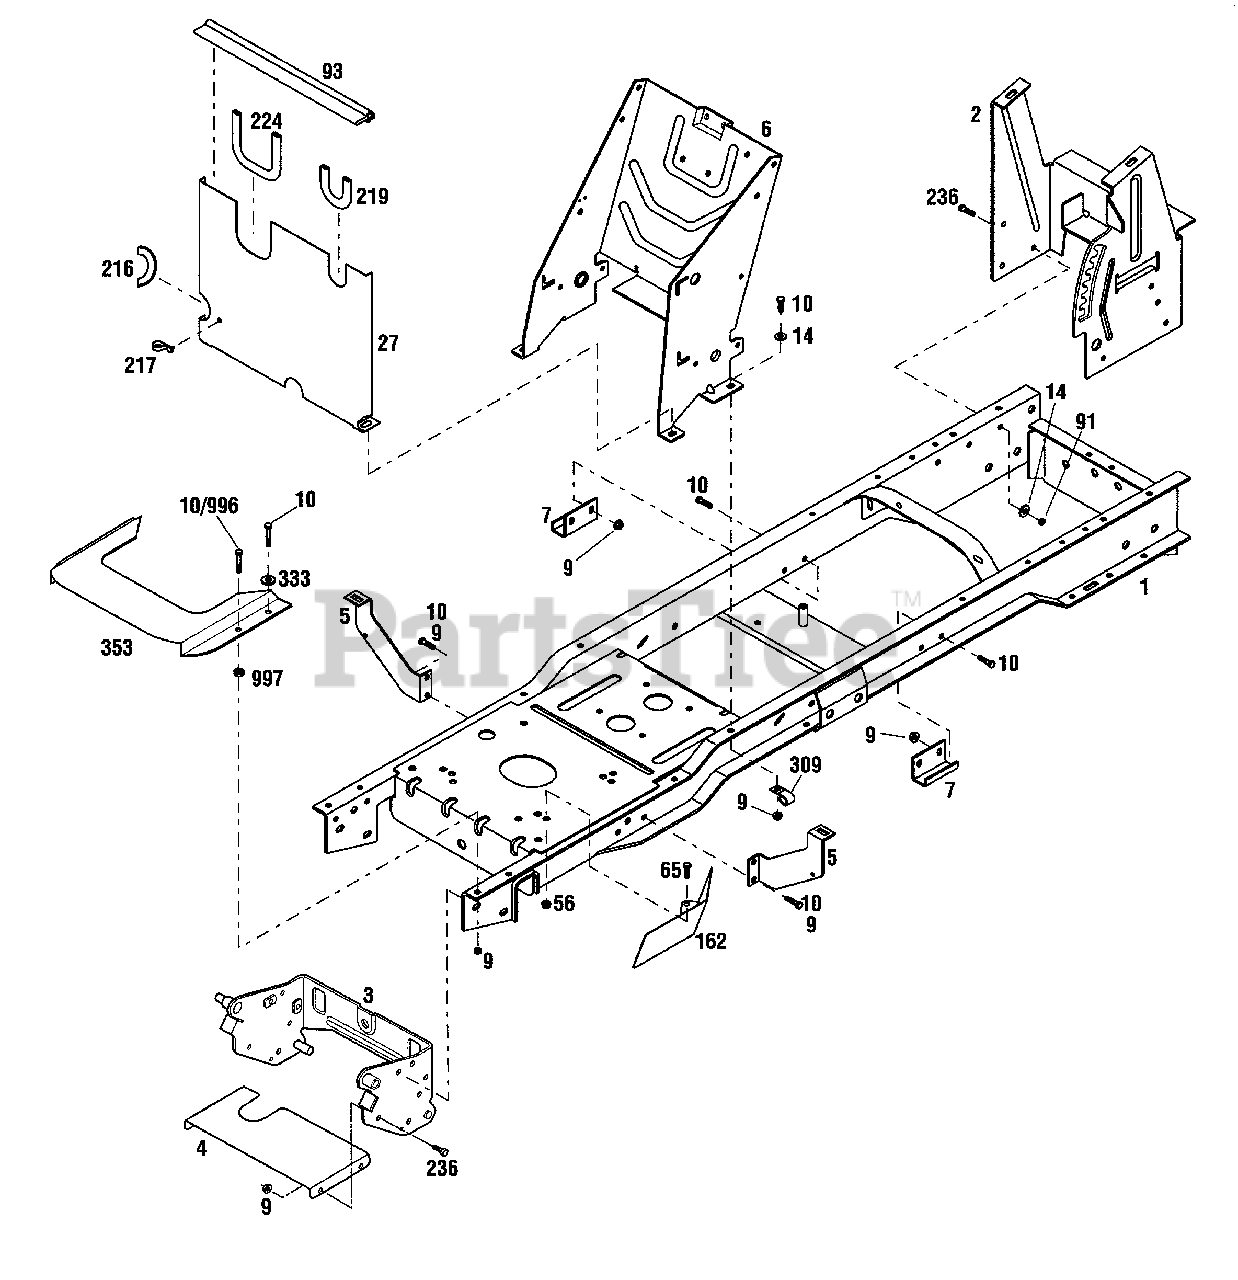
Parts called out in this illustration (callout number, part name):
2	Rear Tank Support
3	Attachment Bracket
4	Heat Shield
5	Fender Support
6	Console Support
7	Mower Stop
9	Flange Nut, 5/16-18
10	Hex Head Screw, 5/16-18 x 3/4
14	Flat Washer, 5/16
27	Heat Shield
56	Flange Nut, 1/4-20
65	Flange Screw, 1/4-20 x 1/2
91	Locknut, 5/16-18
93	Heat Shield Gasket
162	Upper Heat Shield
216	Trim
217	Cable Hanger
219	Trim
224	Trim
236	Flange Screw, 5/16-18 x 3/4
309	J-Clamp
333	Flat Washer, 5/16 x 1-1/2
353	Heat Shield
996	Hex Head Screw, 5/16-18 x 1
997	Spacer
